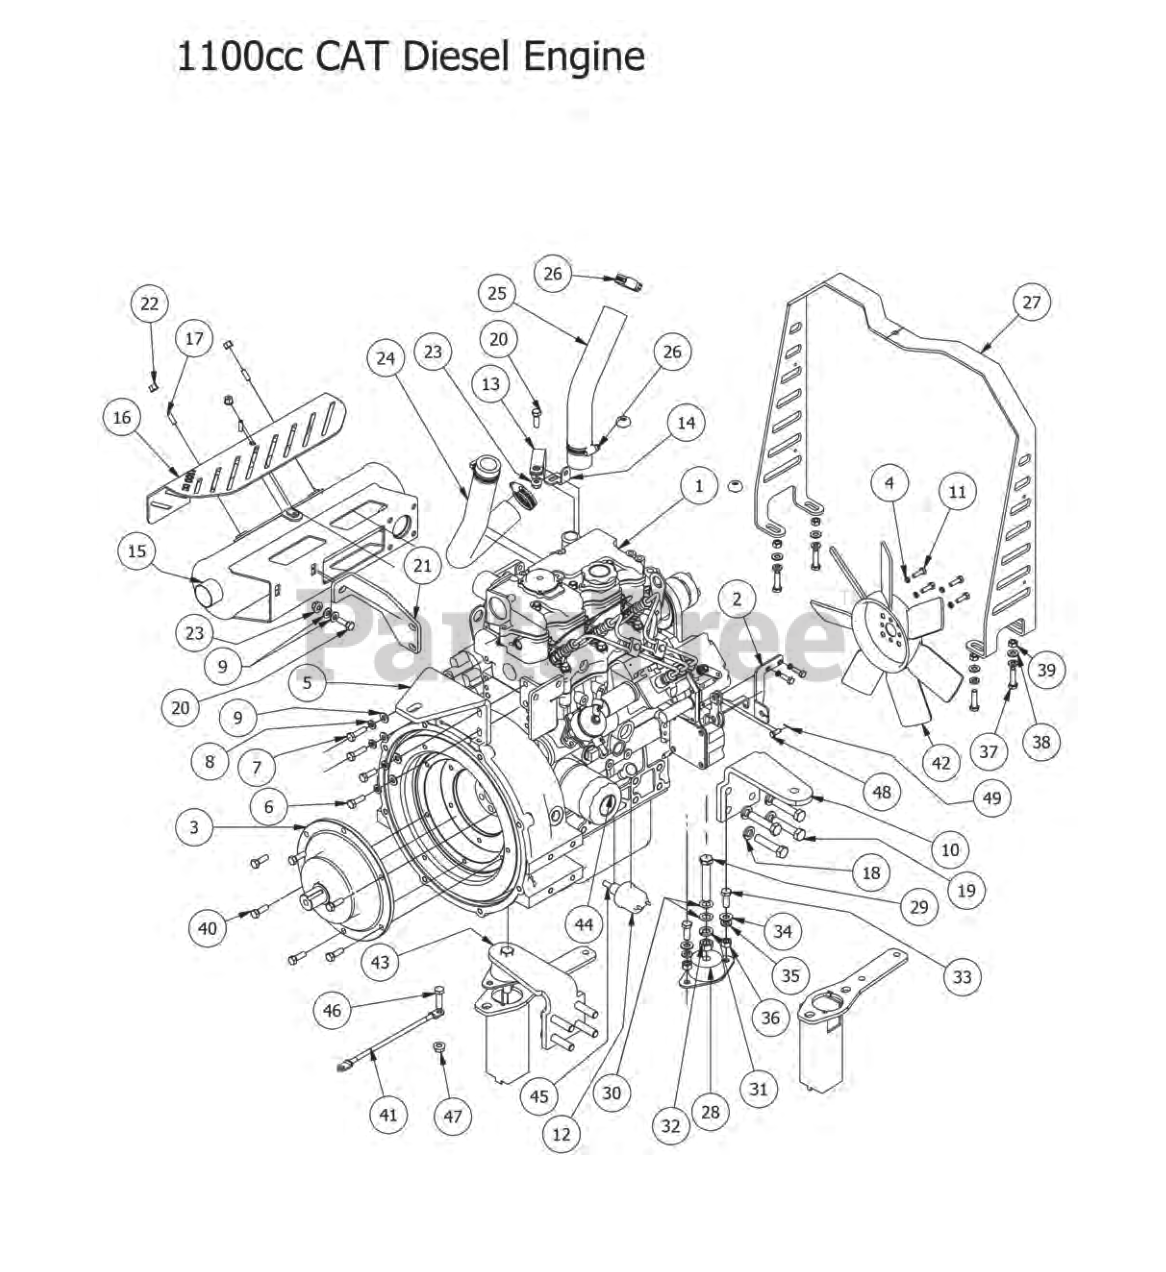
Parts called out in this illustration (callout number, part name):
1	1100cc CAT Diesel Engine
2	Diesel Throttle Bracket (4 Tier)
3	Stub Shaft
4	1/4" Lock Washer
5	Air Cleaner Support Diesel
6	M8 x 1.25 x 25mm Hex Head Bolt
7	M8 x 1.25 x 30mm Hex Head Bolt
8	5/16" Lock Washer
9	5/16" Flat Washer
10	Diesel Motor Side Support Right
11	6mm x 20mm Bolt
12	Pressure sender-2012 Gauge and up
13	Diesel Clamp 1 3/4" Vinyl
14	Diesel Radiator Hose Clamp Bracket
15	28/35hp Caterpillar Muffler
16	Diesel Muffler Guard (28hp)
17	1/4" x 3/4" Set Screw
18	1/2" Lock Washer
19	12mm Bolt- Diesel
20	5/16" x 1" Bolt
21	Muffler Brace Diesel
22	1/4-20 Nylon Insert flange Nut
23	5/16" Flange Nut
24	Bottom Radiator Hose for Diesel
25	Top Radiator Hose for Diesel
26	1 1/8" Hose Clamp
27	Hood Holder Diesel
28	Rubber Isolator
29	1/2" x 3" Hex Bolt
30	1/2" Brass Washer
31	1/2" Lock Washer
32	1/2" Hex Nut
33	3/8" x 1" Hex Bolt
34	3/8" Flat Washer
35	3/8" Lock Washer
36	3/8" Hex Nut
37	5/16" x 1 1/4" Hex Bolt
38	5/16" Flat Washer
40	5/16-18 X 1 Button Head Bolt
41	Starer To Chassis Cable - Diesel
42	Engine Fan - Diesel
43	Diesel Side Motor Mount Left
44	CAT Oil Filter
45	Brass Washer For Weld On Hinge
46	3/8" x 1 1/2" Hex Bolt
47	3/8" Flange Nut
48	1/4-5/8 Clevis Pin
49	3/32 X 1/2 Cotter-pin
